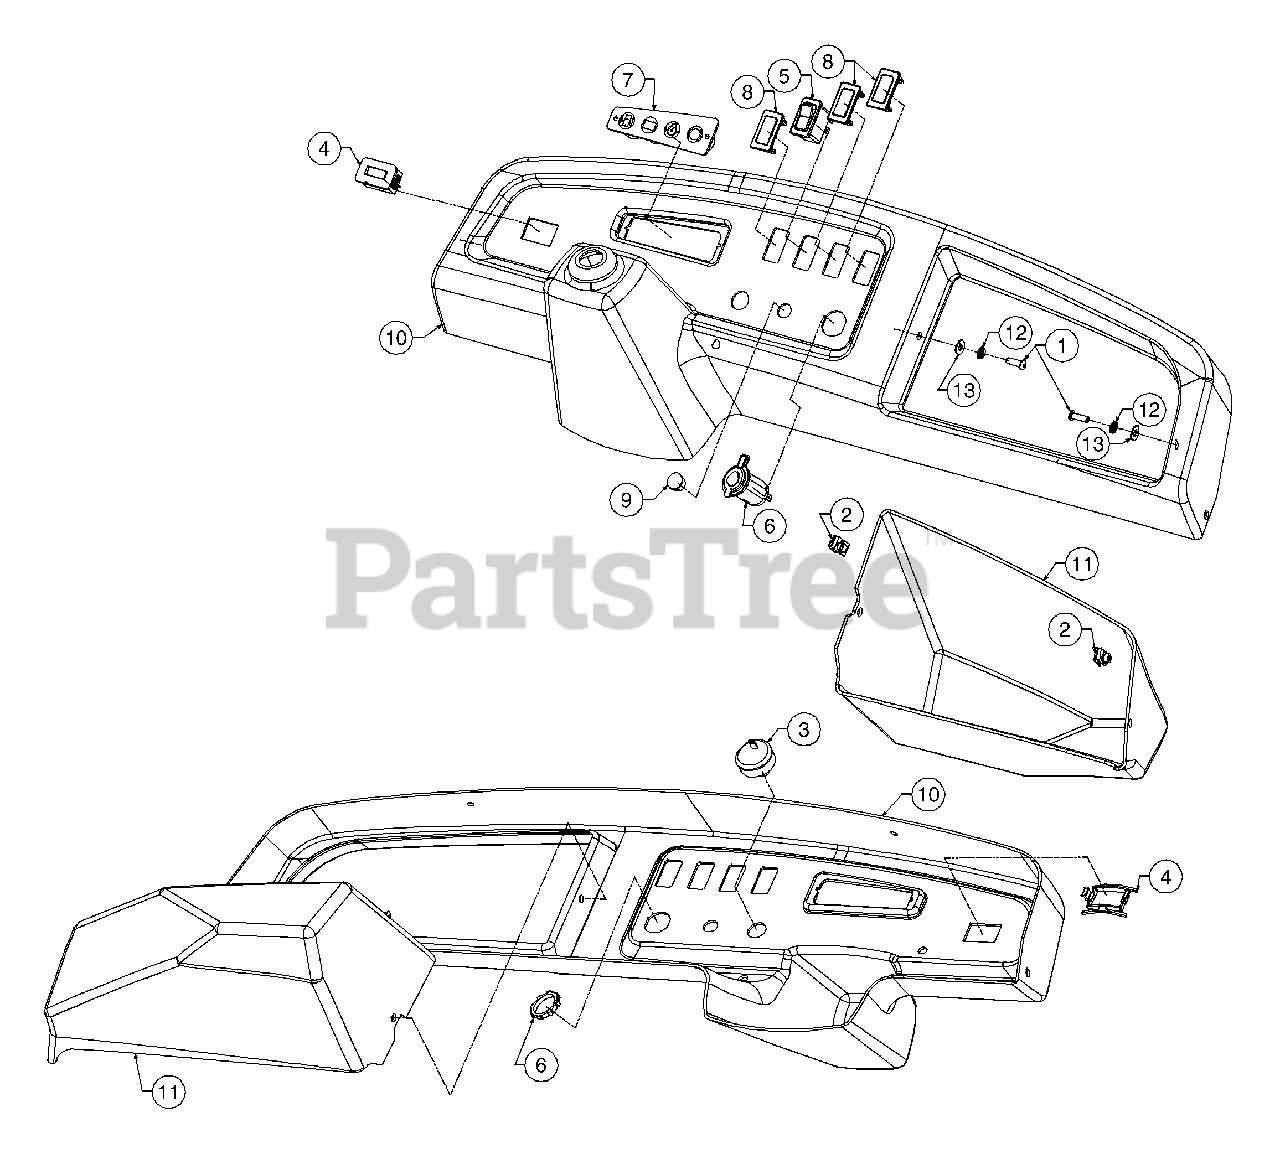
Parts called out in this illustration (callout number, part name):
1	Screw, Machine, 1/4-20 x .75
2	U-Nut, 1/4-20
3	Switch, Key
4	Meter, Hour
5	Rocker Switch, Headlight
6	Recepticle, Power, 12v
7	Housing, Bulb
8	Plug, Switch
9	Plug, Horn Switch
10	Panel, Instrument
11	Box, Glove
12	Washer, Lock, 1/4, Regular Duty
13	Washer, Flat, .271 x .630 x .065
